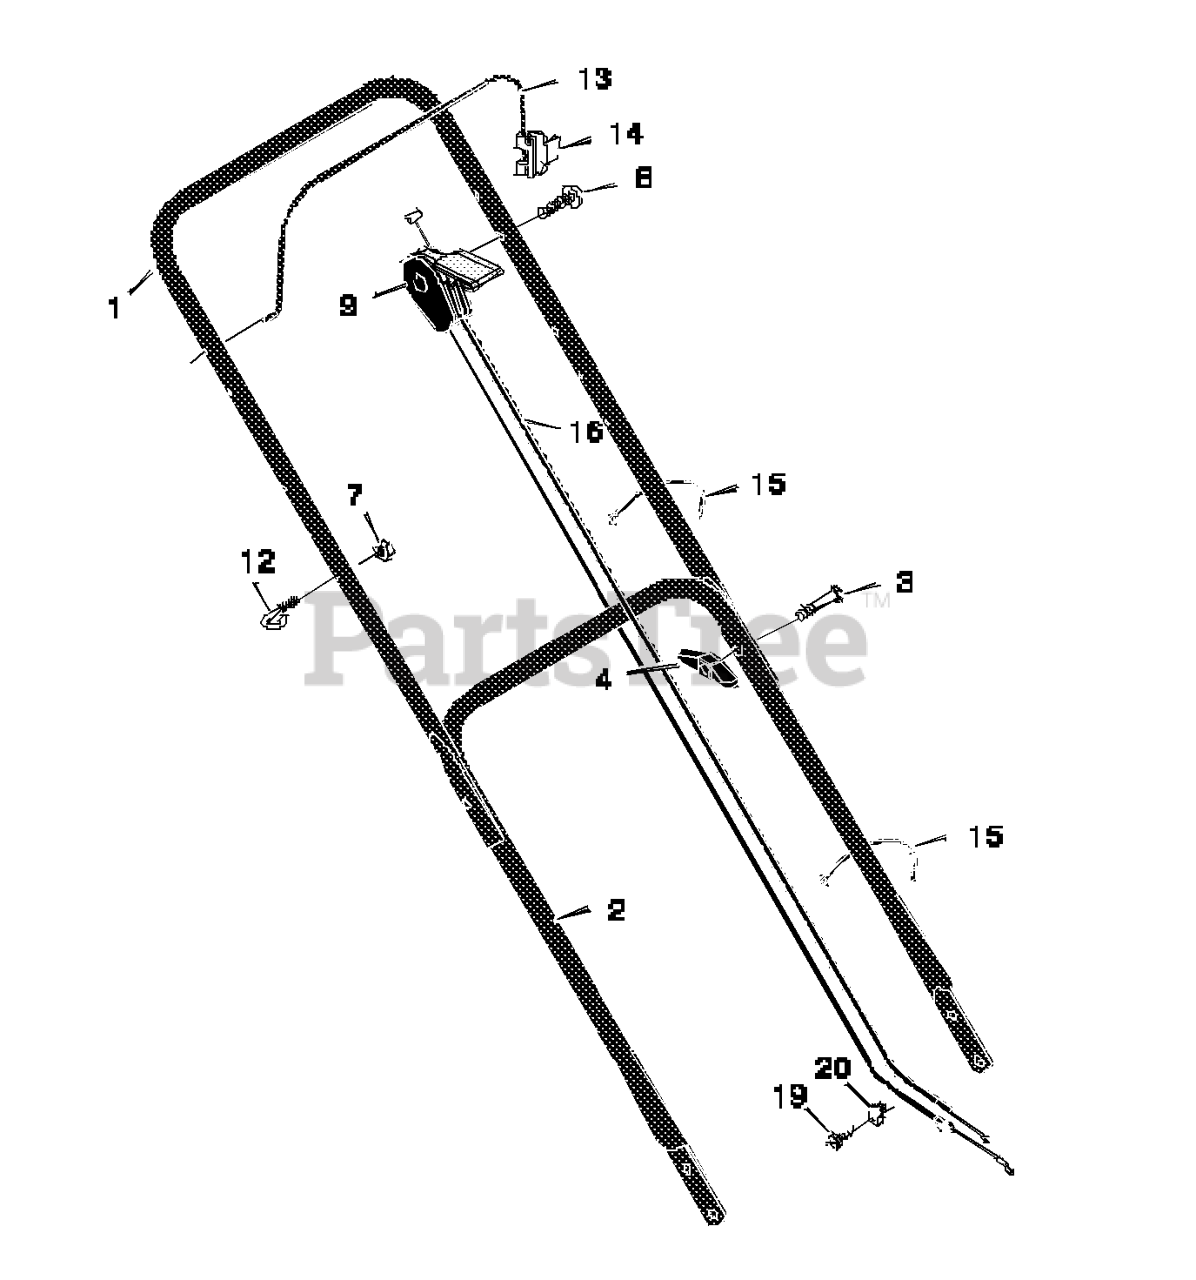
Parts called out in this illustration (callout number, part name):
1	Handle, Upper (Black)
2	Handle, Lower (Black)
4	Knob, Plastic
7	Locknut
9	Throttle Control
12	GUIDE, ROPE
13	Engine Stop Lever
14	Bracket, Stop Lever
15	Fastener, Cable
16	Engine Stop Cable
